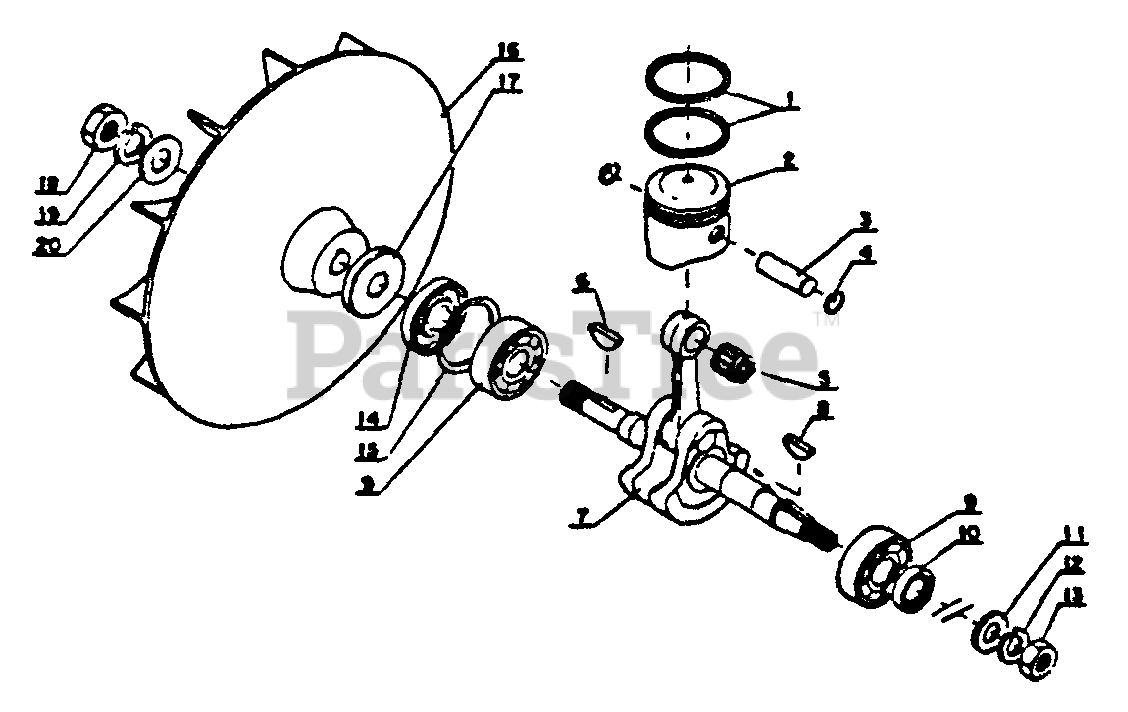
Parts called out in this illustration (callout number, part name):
1	RING, PISTON
2	PISTON
3	PIN, PISTON
4	RING, RETAINING
5	BEARING, NEEDLE
7	CRANKSHAFT ASSY
9	BEARING, BALL - 6201
10	SEAL, OIL
12	LOCKWASHER - 8
14	SEAL, OIL
15	RING, RETAINING - 32
16	FAN
17	WASHER, THRUST
18	NUT - 10
19	LOCKWASHER - 10
20	WASHER - 10
